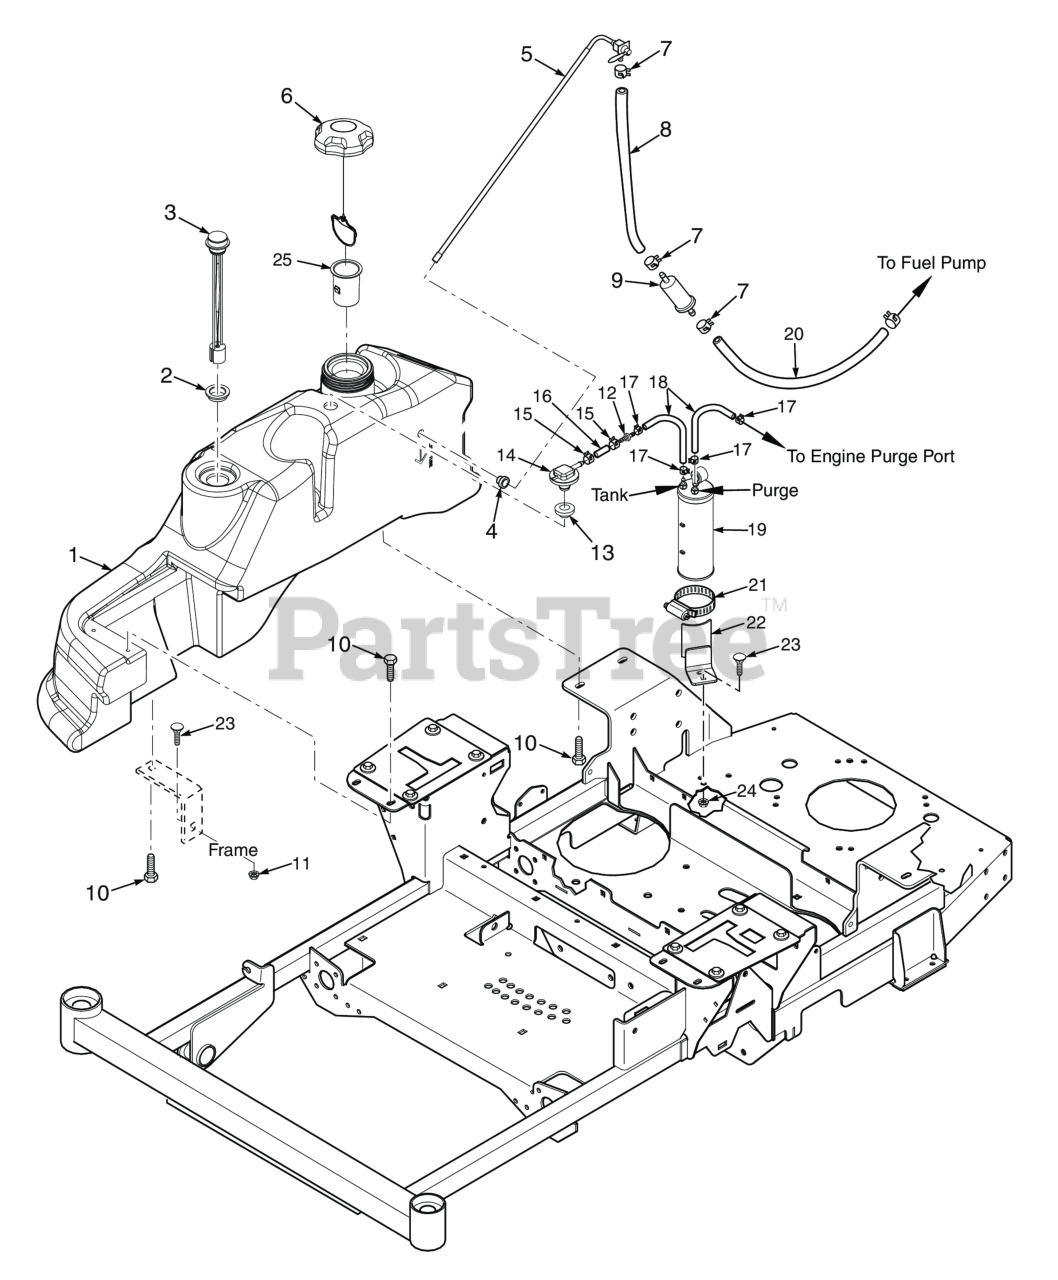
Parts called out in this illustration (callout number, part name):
1	Fuel Tank Assembly - SPZ
2	Grommet, Fuel Gauge
3	Fuel Gauge Assembly
4	Bushing, 0.56" Dia. Viton
5	Fuel Tube Assembly
6	Fuel Cap w/ Tether (E.P.A.)
7	Clamp, Fuel Hose 1/4" Hose I.D.
8	Fuel Hose, 1/4" I.D. Non-Perm (791DFI Fuel Return) - Order by Inch
9	Fuel Filter
10	Capscrew, 5/16-18 x .75 Serrated Flange Hex Head
11	Nut, Flange Head Elastic Stop 5/16-18
12	Mender, 1/4 x 3/16 w/0.02 Hole
13	Grommet, Viton,
14	Remote Vent, No Valve
15	CLAMP, FUEL HOSE(KAWASAKI ONLY)
16	Hose, 1/4" Vapor Recovery (order by inch)
17	Clamp, Vapor Recovery Hose 3/16"
18	Hose, Vapor Recovery 3/16" (order by inch)
19	Carbon Canister - SVR-52V / SVR-61V
20	Fuel Hose
21	Clamp, 3-1/2" Max. Dia.
22	Bracket Weldment - SPZ52H, SPZ-61H-27SR
23	Bolt, 5/16-18 x .75 RHSN Carriage
24	Nut, Serrated Flange 5/16-18 (Right Front Engine Mounting, Briggs and Kohler Only)
25	Tube, Fuel Tank Insert - 4"
